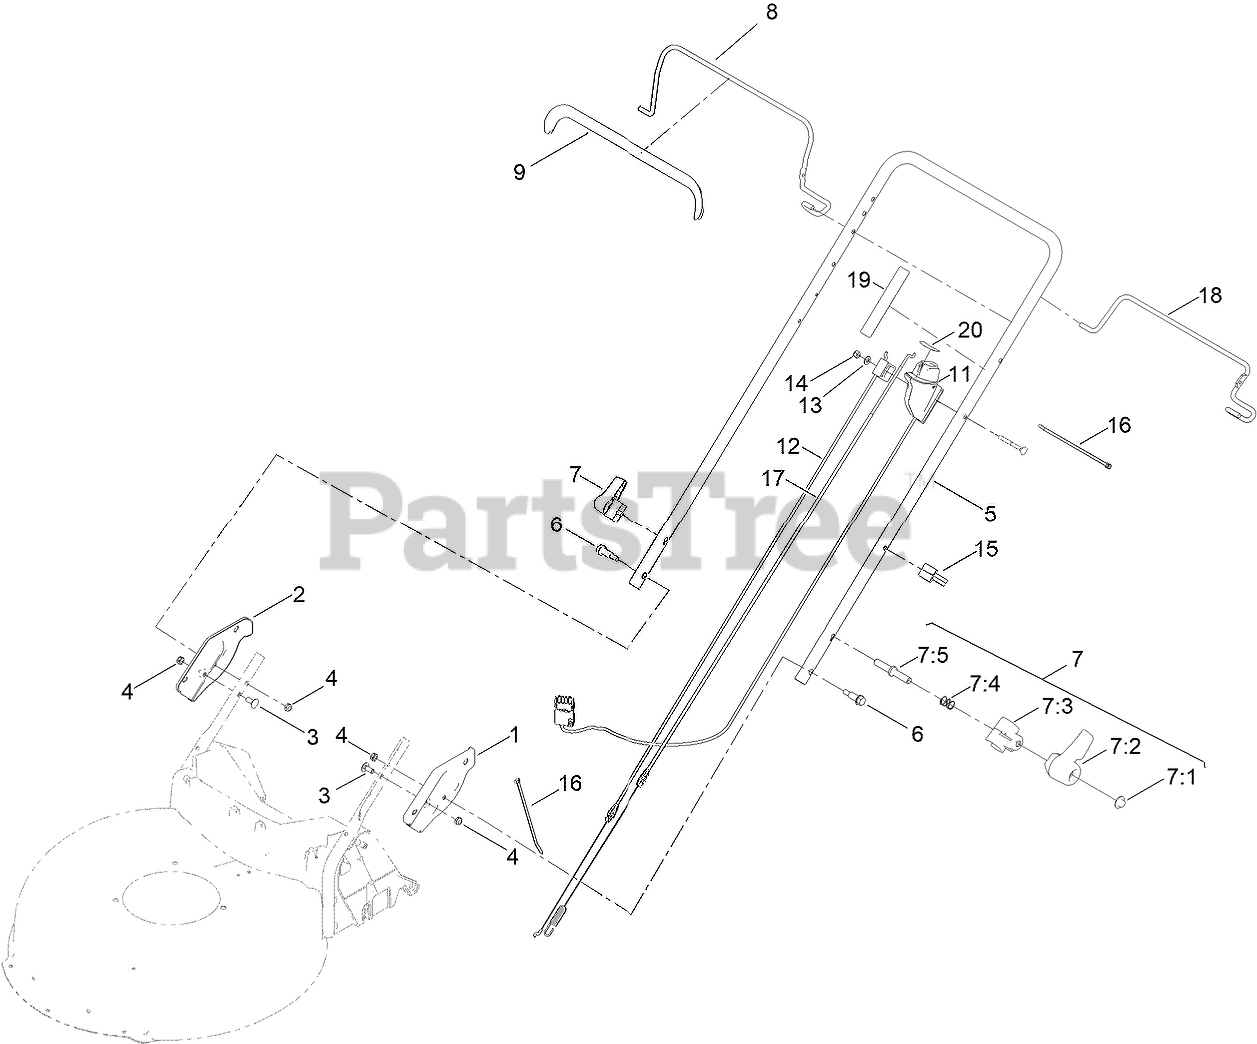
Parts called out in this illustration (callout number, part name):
1	PLATE-HANDLE, LH
2	PLATE-HANDLE, RH
3	BOLT-CARR
4	NUT-HEX
6	BOLT-SHOULDER, HHF
7	QUICK RELEASE ASM
7:1	NUT-PUSH
7:2	LEVER-RELEASE
7:3	ANCHOR-SPRING
7:4	SPRING-COMPRESSION
7:5	ROD-RELEASE
8	BAIL-BRAKE
9	COVER-BAIL
11	SWITCH STARTER ASM
12	CABLE-BRAKE, HP
13	WASHER-FLAT
14	NUT-LOCK, NI
15	GUIDE-CABLE
16	TIE-CABLE
17	CABLE-TRACTION
18	BAIL-TRACTION
19	DECAL-CONTROLS (60V START)
20	DECAL CONTROL SPEED
